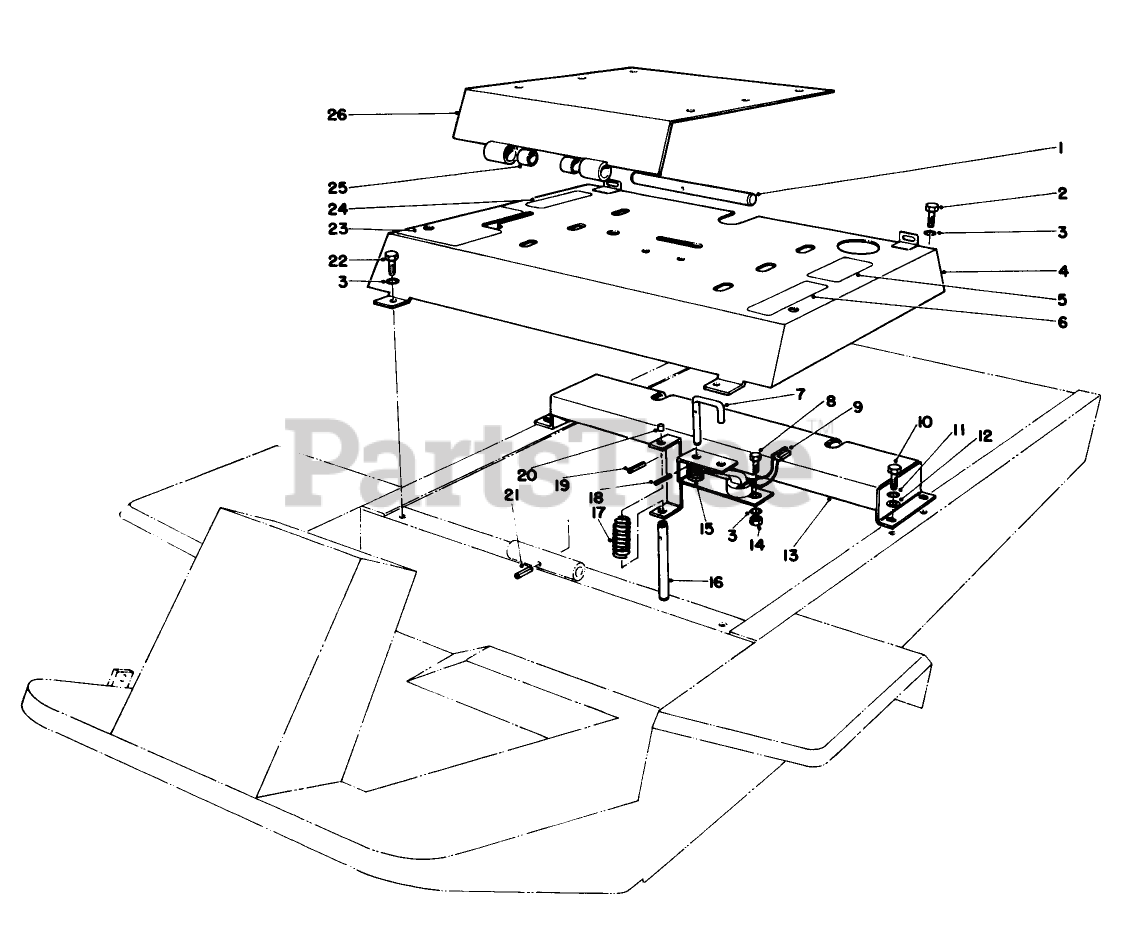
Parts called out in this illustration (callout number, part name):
1	SHAFT-PIVOT, SEAT
2	SCREW-HH
3	WASHER-LOCK
4	Cover-Seat Support (Incl. Ref. #5, 6, 23 & 24)
5	DECAL-REFUELING
6	Decal Caution
7	SEAT SWITCH PIN
8	SCREW-HH
9	SEAT SWITCH
10	SCREW-HH
11	WASHER-LOCK
12	WASHER-FLAT
13	Seat Support
14	NUT-HEX
15	SPRING
16	PIN-SWITCH, SEAT
17	SPRING-COMP
18	PIN-SPRING
19	PIN-ROLL, SLOTTED
20	PIN-PEDAL
21	PIN-ROLL, SLOTTED
22	SCREW THD 1/4 20 5/8
23	Decal Hydraulic Lift
24	Decal Caution
25	.503ID X .875LG BSHG
26	Seat Mount (Incl. Ref. #25)
